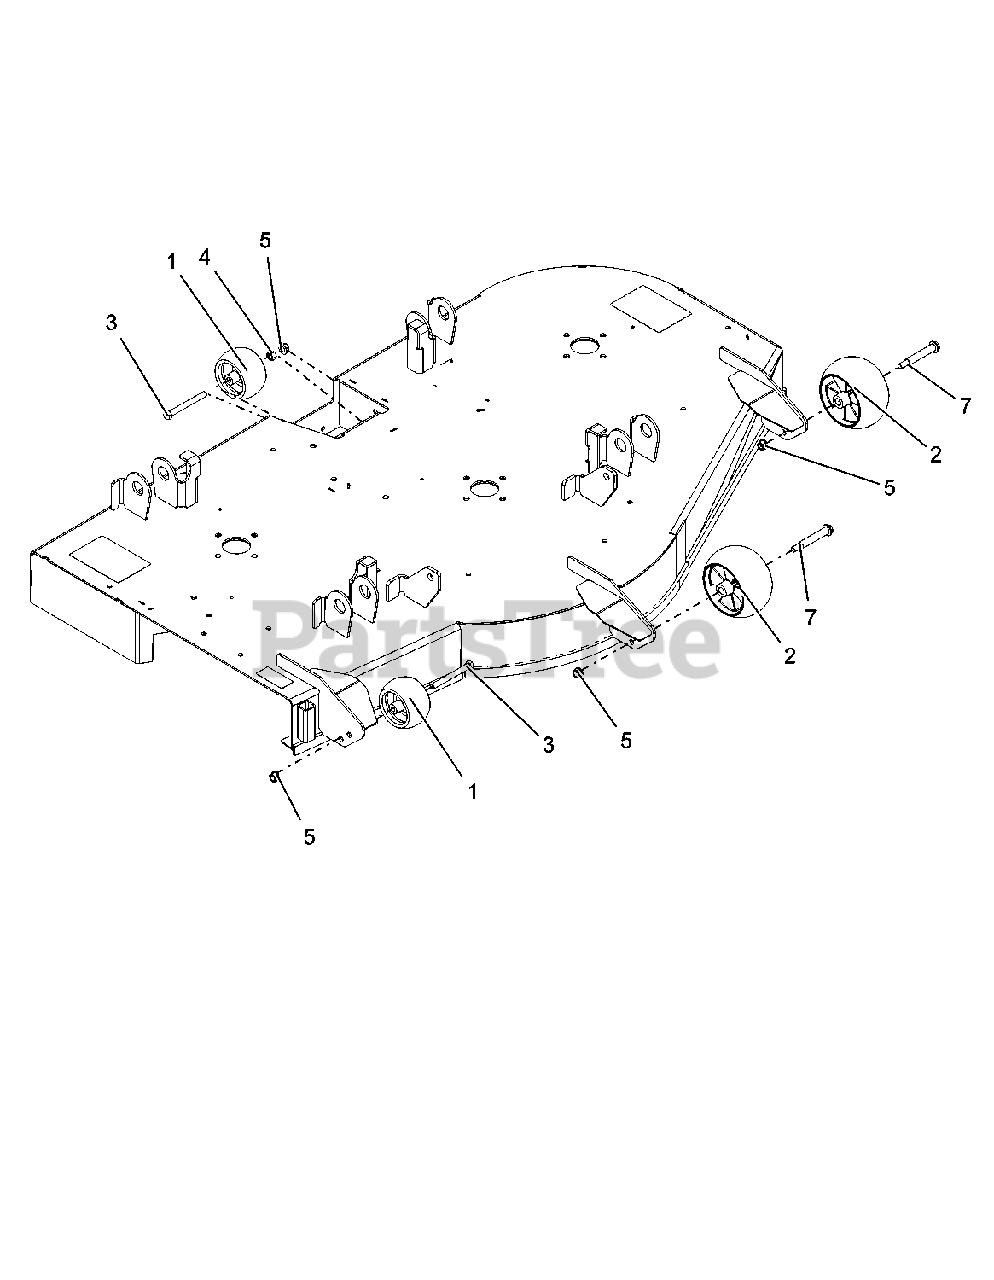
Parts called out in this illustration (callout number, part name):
2	ANTI-SCALP WHEEL - 5X OS
3	@BLT-HEX .38-16X3.50 GR5 YWZC
4	@NUT-HEX .38-16 YWZC
5	@NUT-LK-TOP-FLG .38-16 YWZC
7	BLT-SHLDR .38-16X2.50 HWH G5
